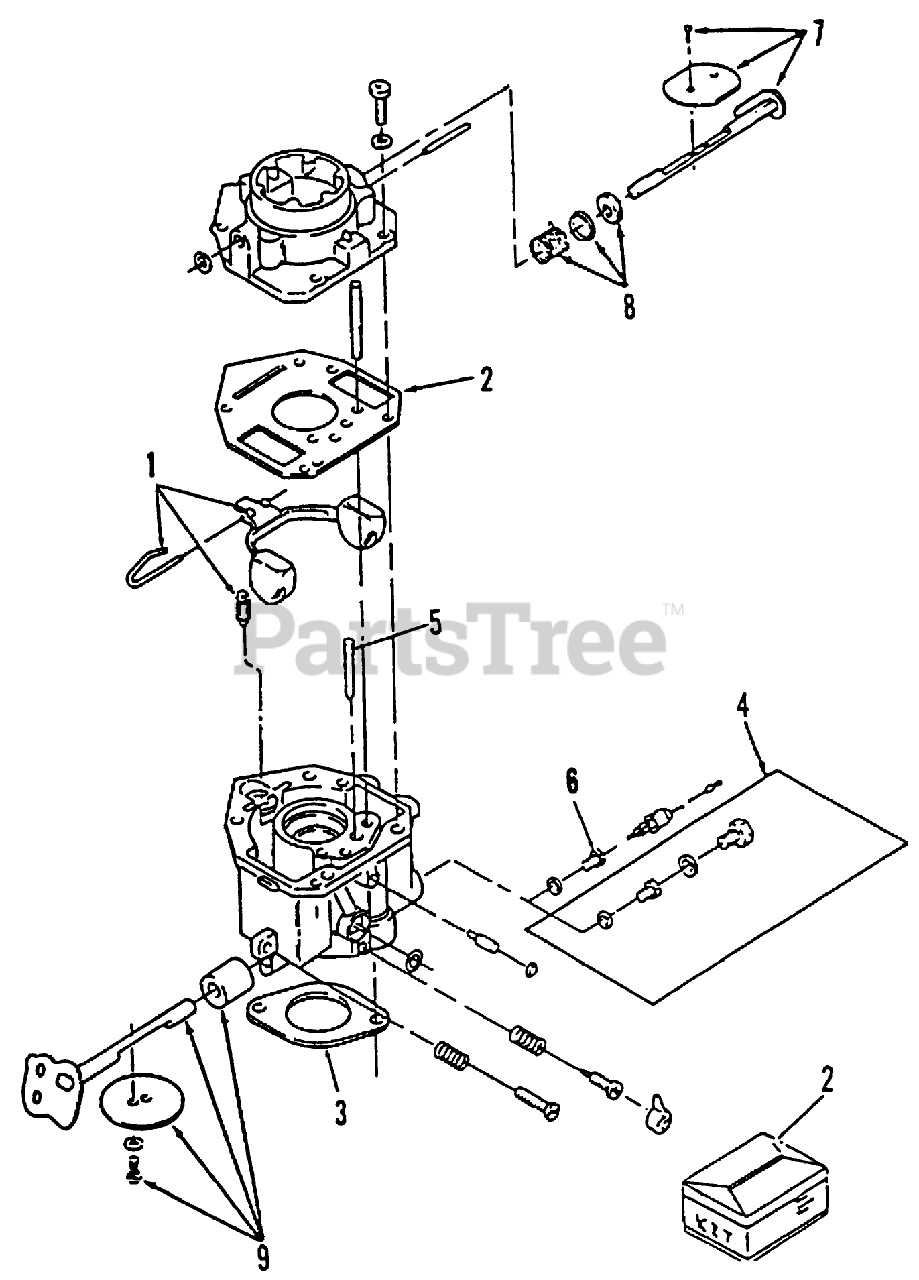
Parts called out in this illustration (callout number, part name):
2	REPAIR KIT
3	GASKET-CARBURETOR
8	CHOKE-LEVER KIT
